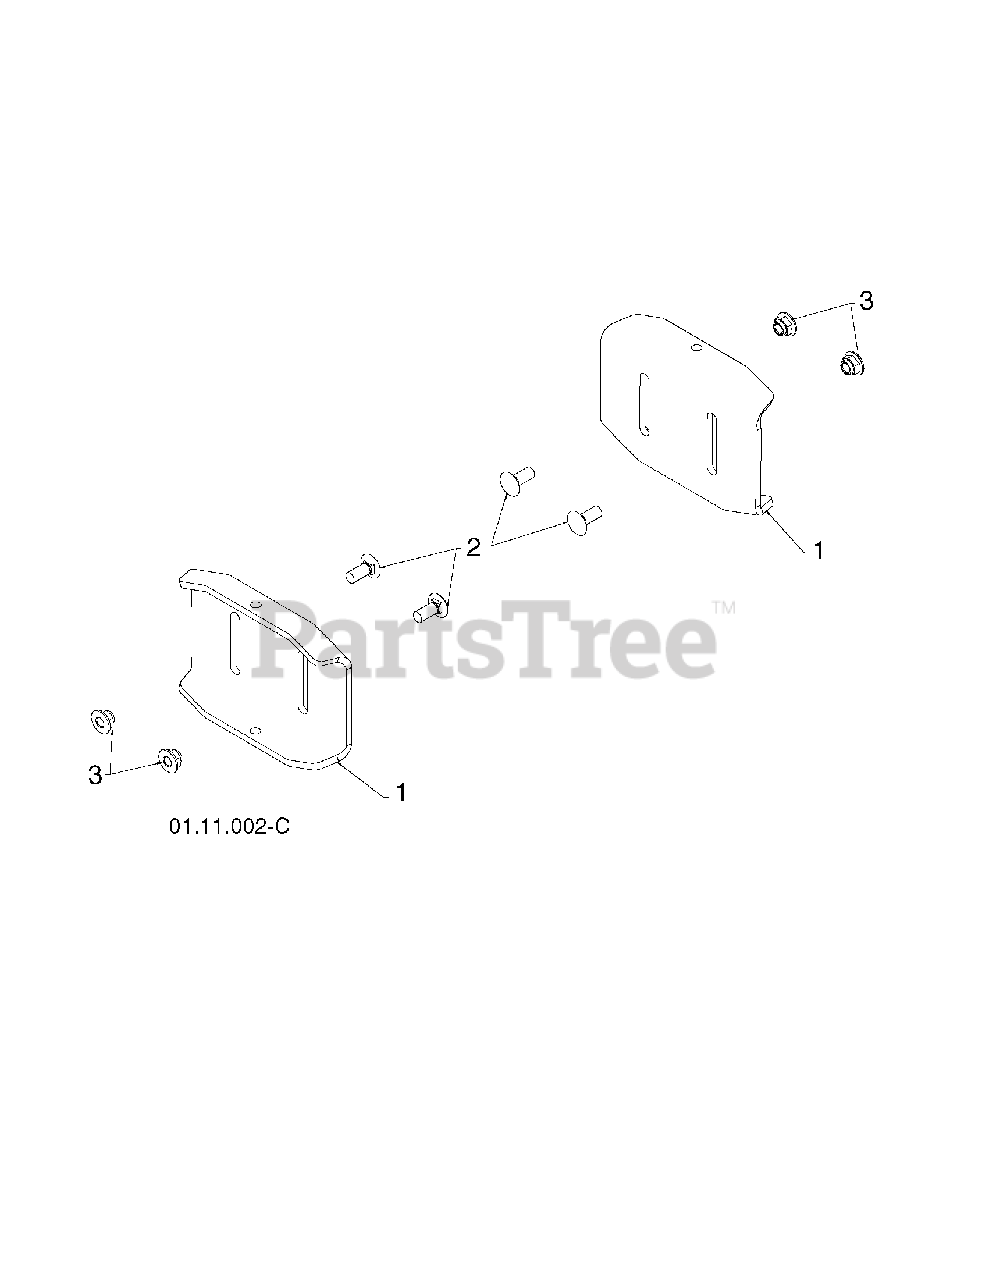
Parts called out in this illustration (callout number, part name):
1	SKID PLATE
2	BOLT
3	NUTNYLOK.FLRANGE.5/16-18
